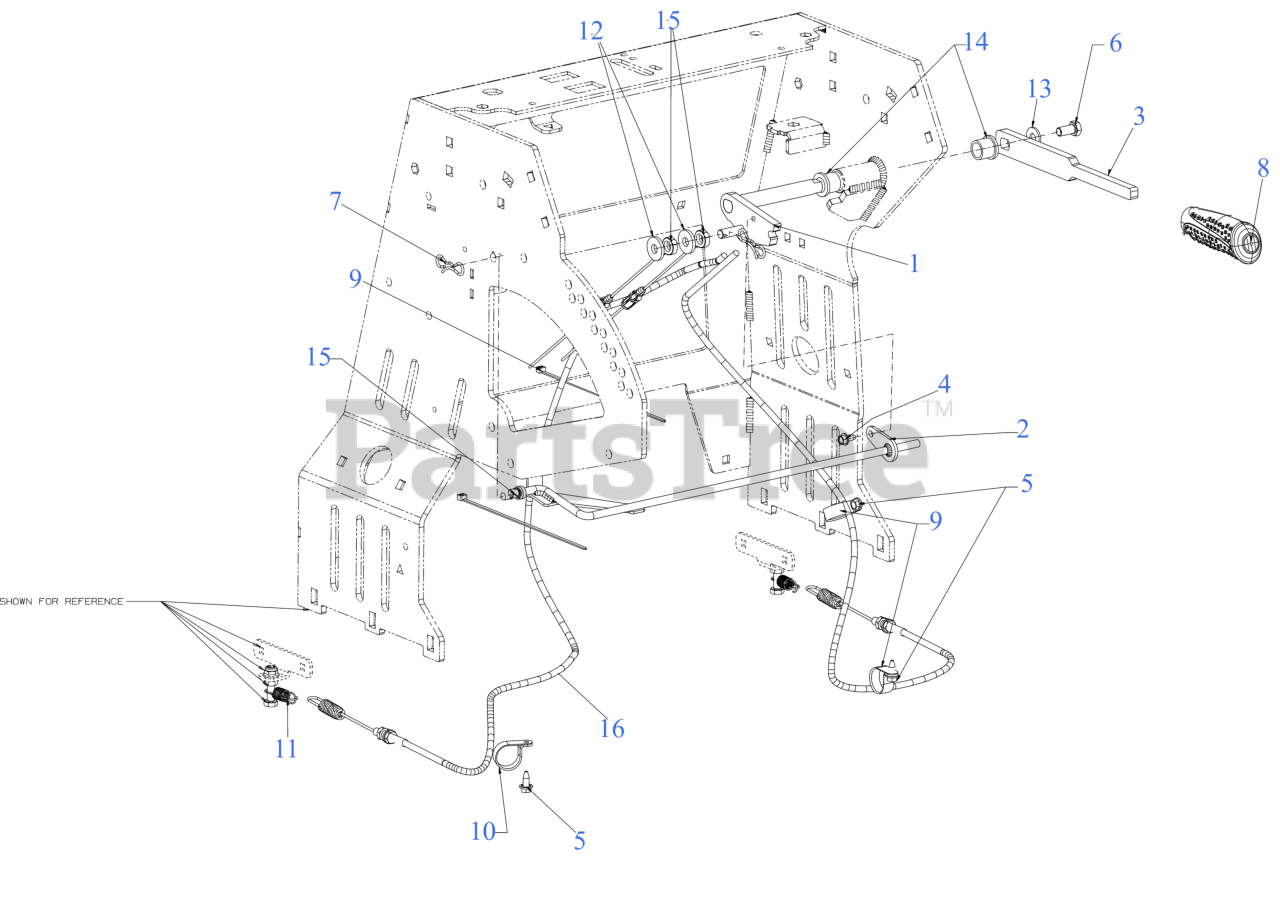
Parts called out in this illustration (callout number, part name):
1	BRAKE PIVOT
2	CONTROL LOCK ROD
3	BRAKE HANDLE
3	HANDLE BRACKET
4	SCREW 1/4-20 X.500
5	SCREW 1/4-20X.625
6	SCREW 3/8-16 x .75 GR 5
7	PIN:COTTER
9	TIE CABLE 8.5 LG
10	DRAIN HOSE CLAMP
11	EXTENSION SPRING .500 OD x 1.71
12	FLAT WASHER .385 x 1.00 x .135
13	FLAT WASHER .385X.870X.090
14	FLANGE BEARING
15	BUSHING .3135ID
16	BRAKE CABLE
